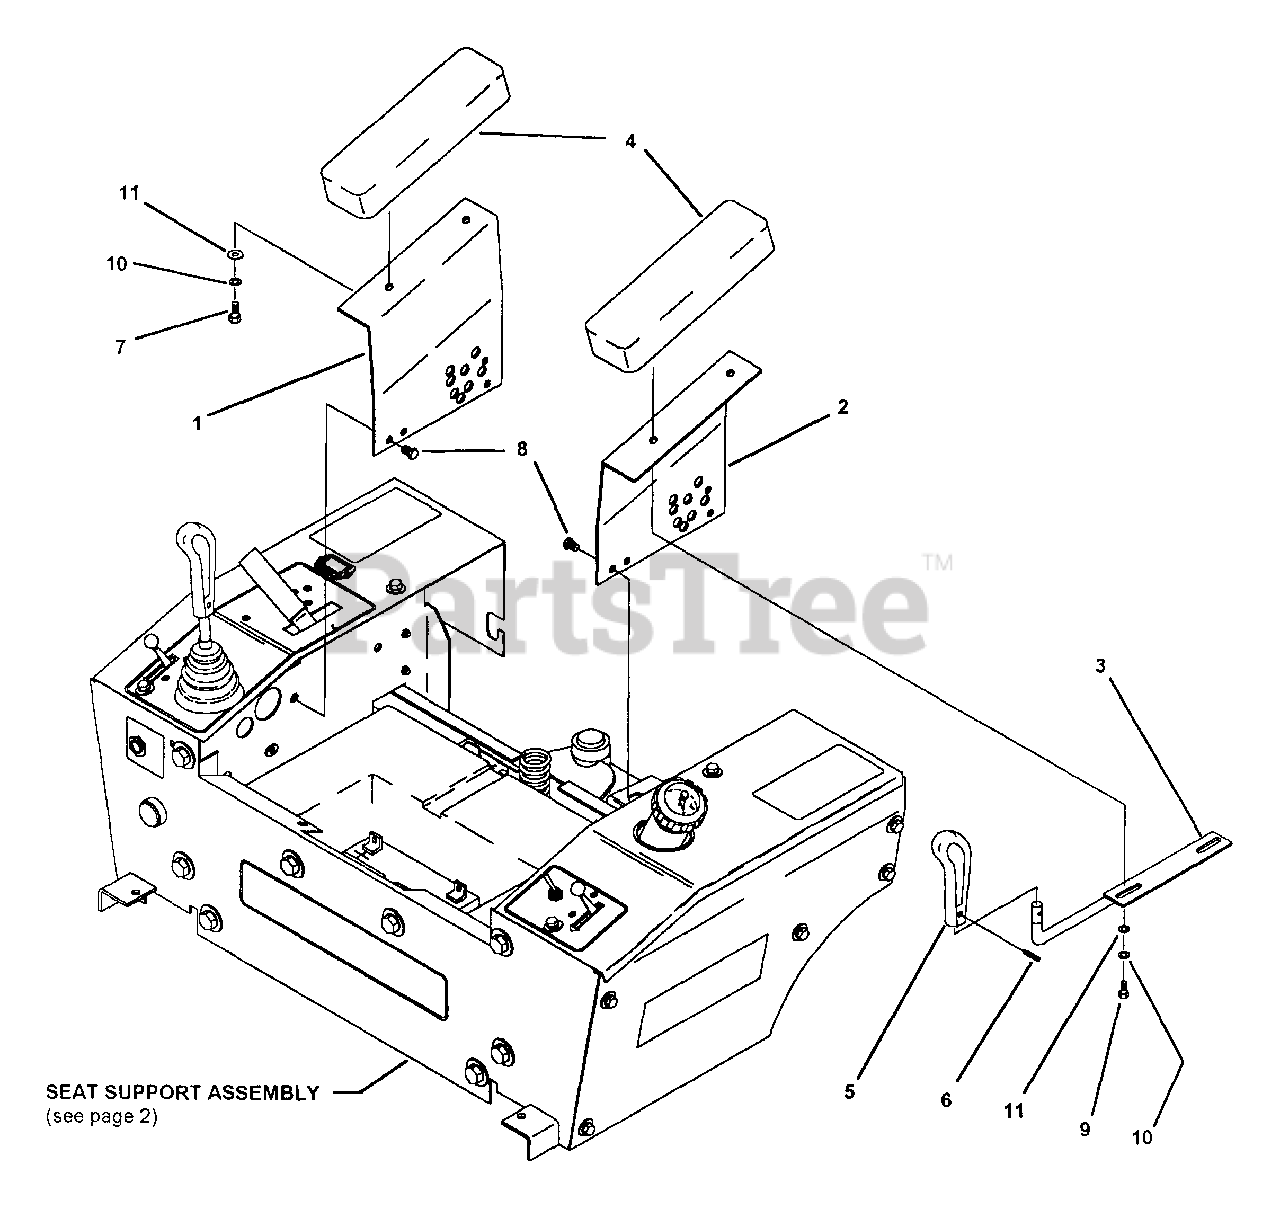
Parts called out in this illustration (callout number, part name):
1	ARM REST SUPPORT R.H.
2	ARM REST SUPPORT L.H.
3	SECURITY HANDLE WELDMENT
4	ARM REST PAD ASSEMBLY
5	HANDLE, JOYSTICK, 7/16" BORE
6	PIN, SPIRAL 3/16 X 1" LIGHT DUTY
7	BOLT, 5/16-18 X 3/4" GR. 5
8	BOLT, 3/8-16 X 1/2" NYLON PATCH
9	BOLT, 5/16-18 X 1" GR. 5
10	LOCKWASHER, 5/16" HEAVY SPRING
11	WASHER, FLAT STD. 5/16"
